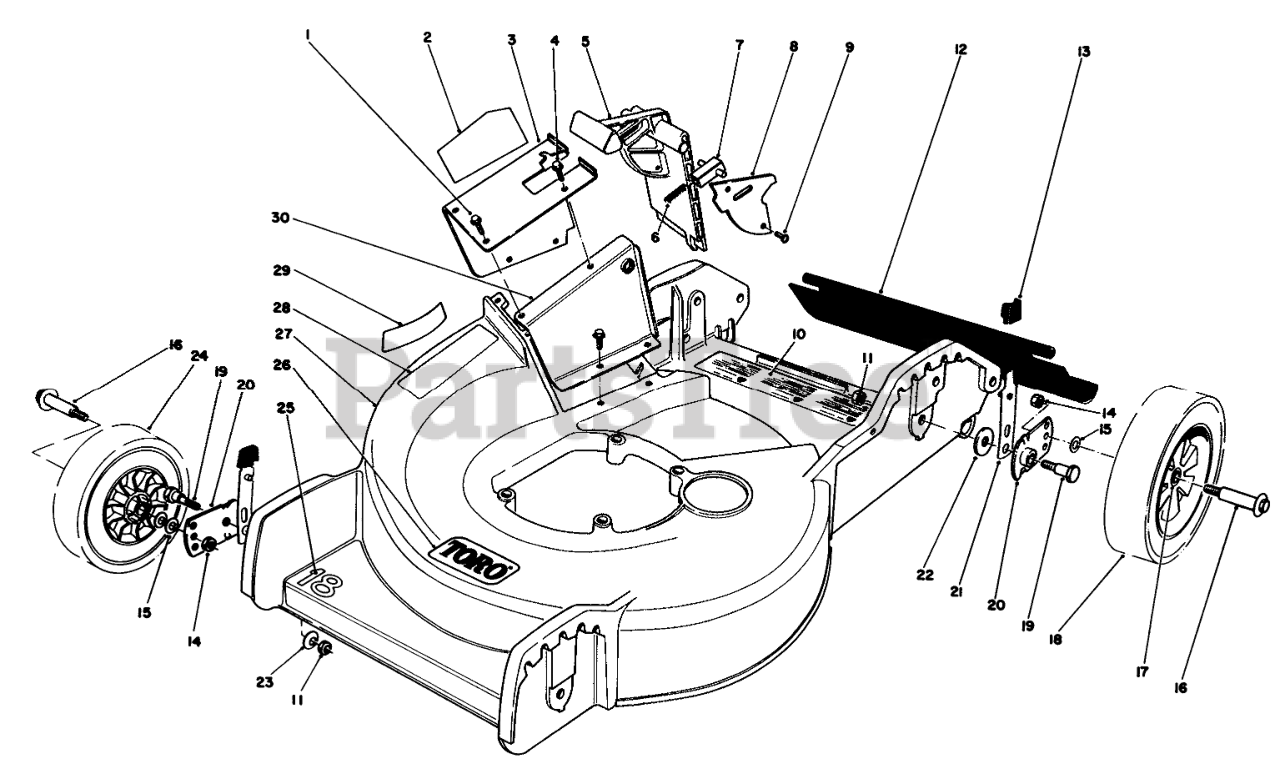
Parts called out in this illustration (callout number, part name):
1	SCREW
2	Decal-Danger
3	Tunnel-Outer (Incl. Ref. #2)
4	SCREW
5	Door Mulching
6	SPRING-COMPRESSION, LATCH
7	Door Latch
8	Cover Door
10	Decal-Danger
11	NUT-LOCK, NI
12	SHIELD - TRAILING
13	KNOB-ARM
14	Nut
15	WASHER
16	BOLT-WHEEL
17	BUSHING
18	Wheel & Tire Assembly (Incl. Ref. #17)
19	5/16-18 PIVOT SCREW
20	PIVOT ARM ASSY
21	SPRING ARM ASM
22	PIVOT WASHER
23	WASHER-BELLEVILLE
24	Wheel & Tire Assembly (Incl Ref. #17)
25	Decal
26	Decal Tow
27	Housing (Incl. Ref. #10)
28	Decal-Step Pad
29	STEP PAD DECAL
30	Tunnel-Inner
